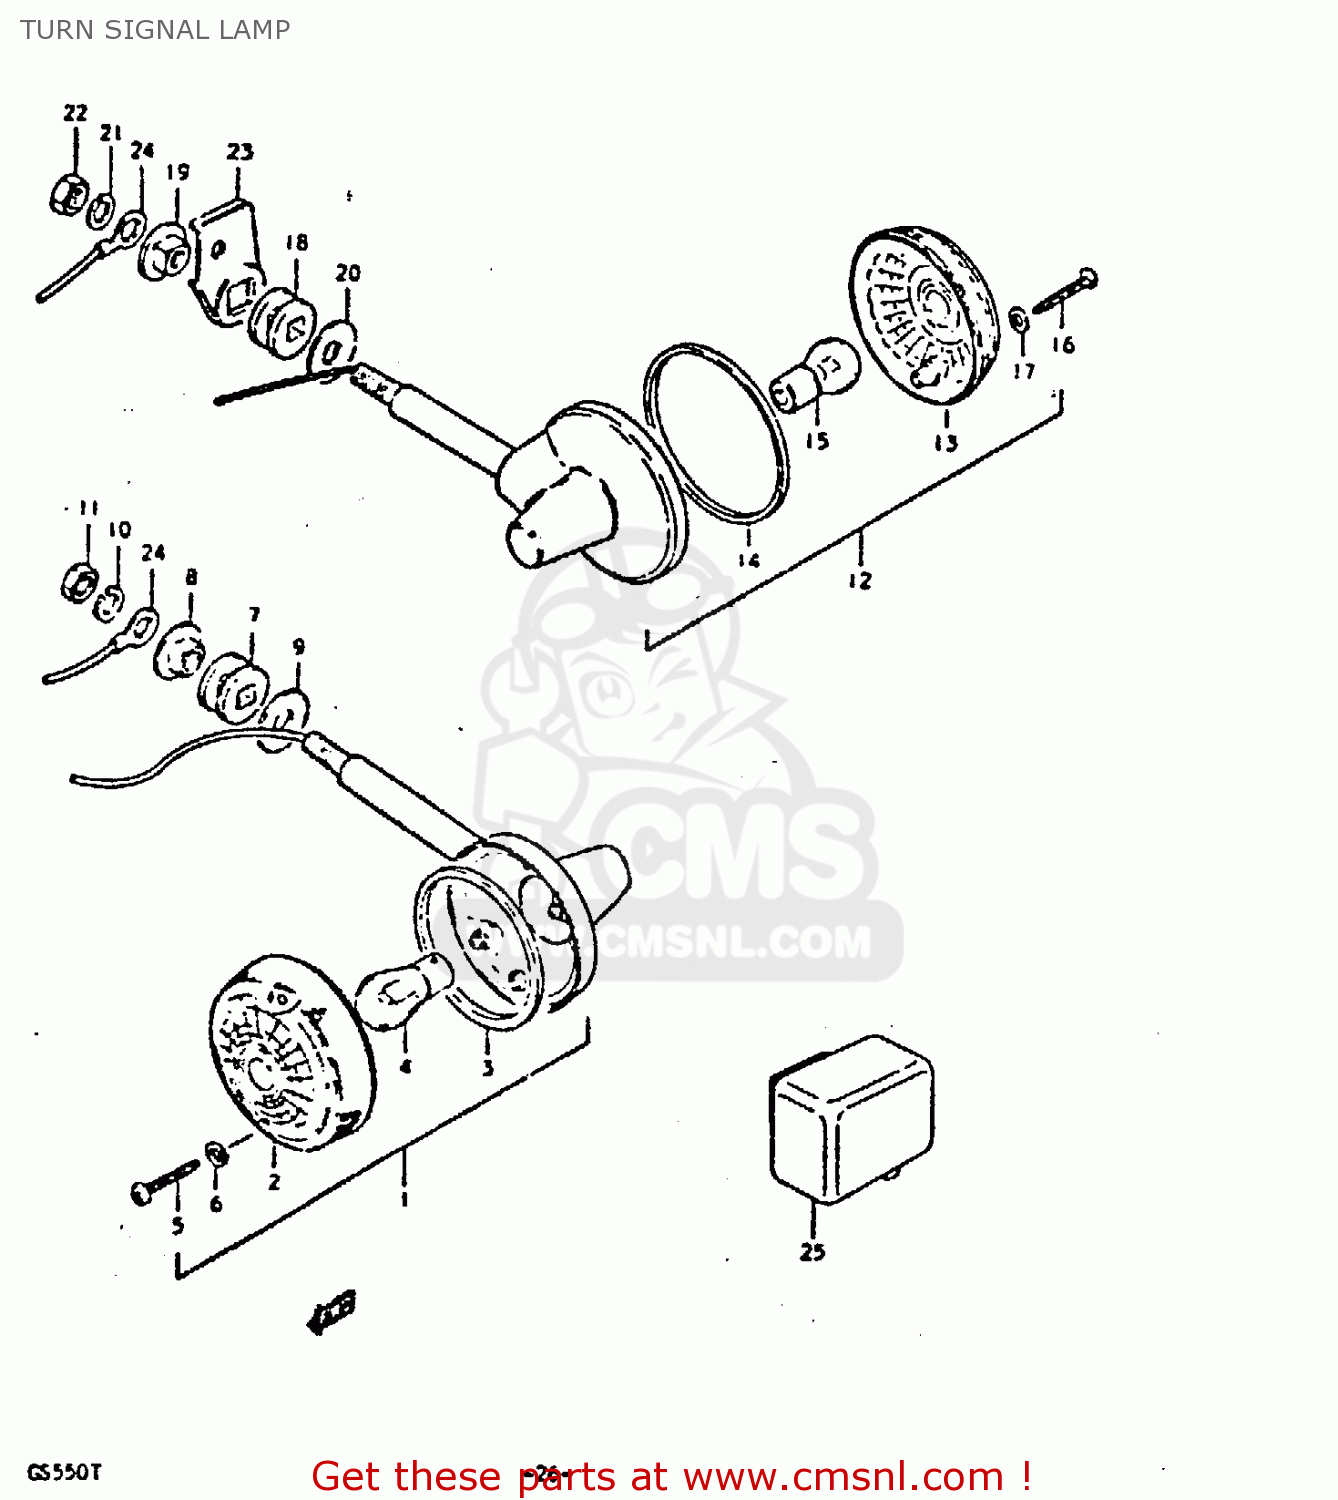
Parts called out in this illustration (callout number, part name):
1	LAMP ASSY, FRONT TURN SIGNAL
2	LENS
3	GASKET (NAS)
4	BULB(12V23W,STANLEY,A4577A)
5	SCREW
6	GASKET (NAS)
7	CUSHION
8	SPACER,RR TURNSIGNAL LAMP
9	WASHER
10	LOCK WASHER
11	NUT
12	LAMP ASSY, FRONT TURN SIGNAL
13	LENS
14	GASKET (NAS)
15	BULB(12V23W,STANLEY,A4577A)
16	SCREW
17	GASKET (NAS)
18	CUSHION
19	SPACER,RR TURNSIGNAL LAMP
20	WASHER
21	LOCK WASHER
22	NUT
23	BRACKET,RR TURNSIGNAL LAMP,R
24	WIRE
25	RELAY,TURN SIGNAL
